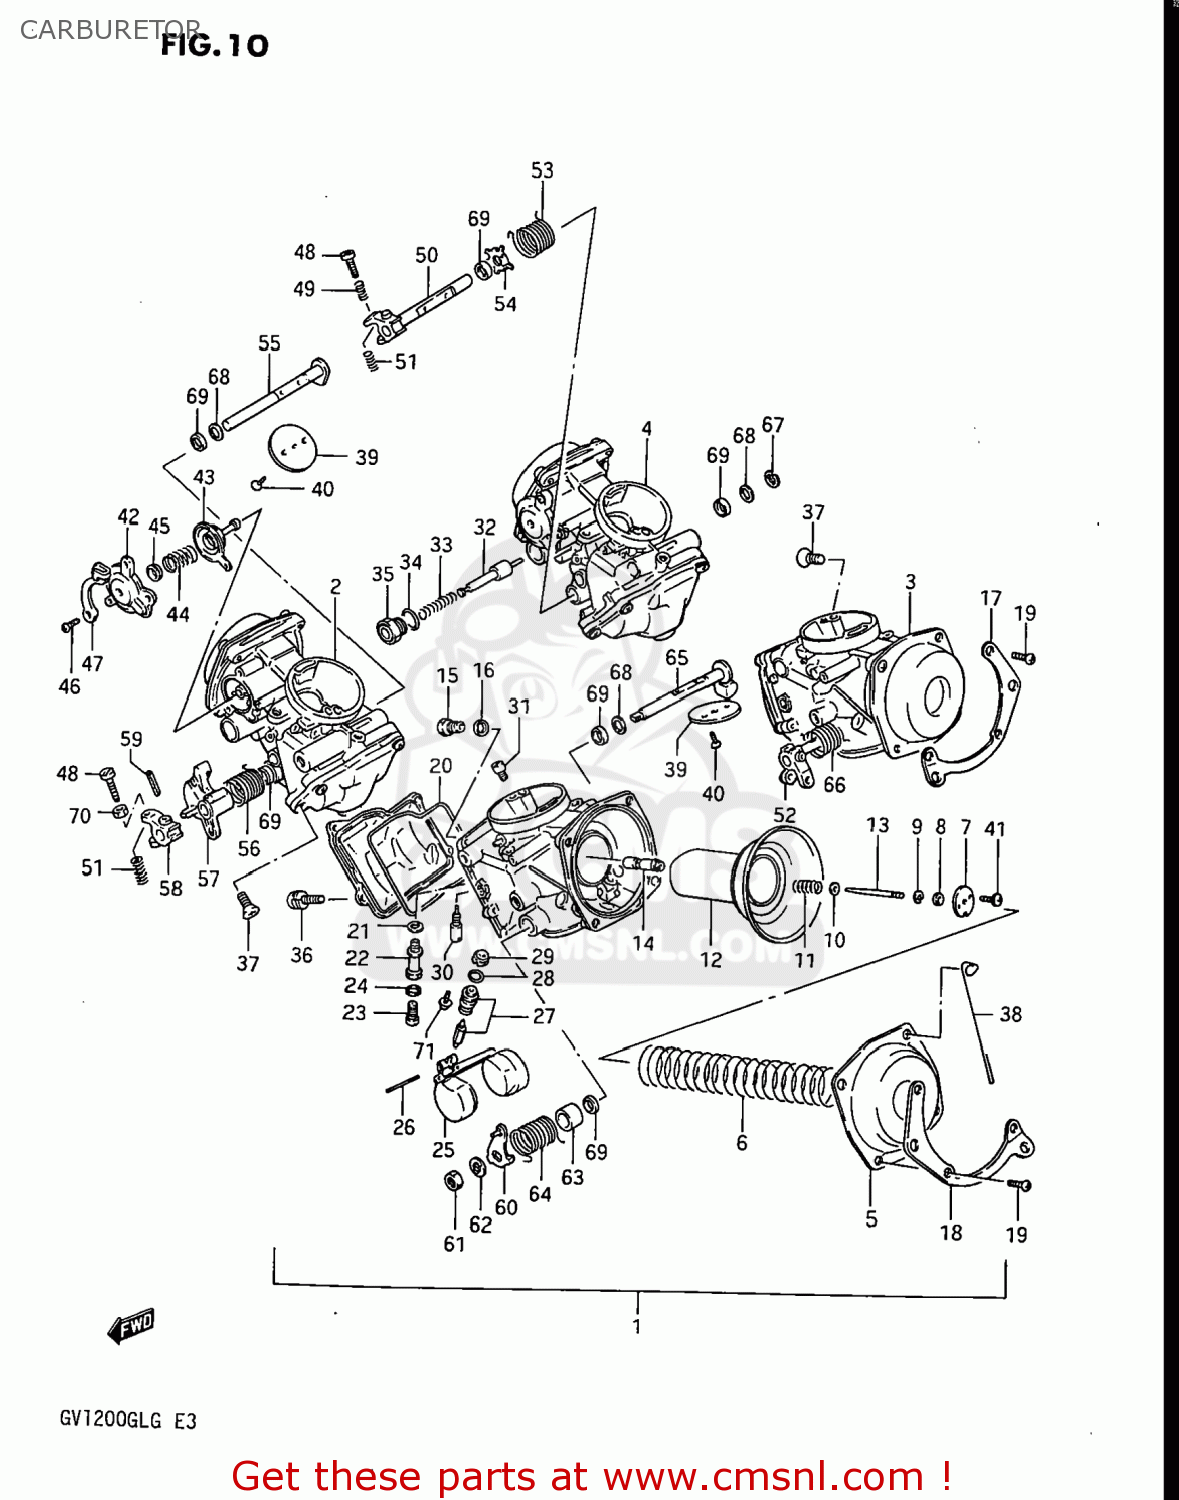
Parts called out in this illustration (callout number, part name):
1	CARBURETOR ASSEMBLY
2	CARBURETOR ASSEMBLY
3	CARBURETOR ASSEMBLY
4	CARBURETOR ASSEMBLY
5	COVER
6	SPRING,DIAPHRAGM
7	PLATE
8	RING
9	CLIP,NEEDLE
10	WASHER
11	SPRING
12	DIAPHRAGM,CARBURETOR
13	NEEDLE JET
14	JET,NEEDLE
15	SCREW
16	WASHER,NEEDLE NOZZLE
17	BRACKET
18	BRACKET
19	SCREW 5X10
20	GASKET,FLOAT CHAMBER
21	GASKET (NAS)
22	HOLDER,MAIN JET
23	JET,MAIN 107,5
24	WASHER
25	FLOAT
26	PIN,FLOAT
27	VALVE ASSEMBLY,NEEDLE
28	O-RING,NEEDLE VALVE
29	FILTER
30	JET,PILOT
31	JET,ENRICH
32	PLUNGER
33	SPRING,STARTER PLUNGER
34	O RING
35	HOLDER,GUIDE
36	SCREW
37	SCREW
38	CLIP
39	VALVE,THROTTLE
40	SCREW
41	SCREW
42	COVER
43	DIAPHRAGM ASSY
44	SPRING
45	PLATE
46	SCREW
47	BRACKET
48	SCREW
49	SPRING
50	SHAFT,THROTTLE
51	SPRING,THROTTLE SCREW
52	SHAFT,THROTTLE
53	SPRING,THROTTLE VALVE
54	PLATE
55	SHAFT,THROTTLE
56	SPRING,THROTTLE VALVE
57	LEVER,THROTTLE
58	LEVER,THROTTLE
59	PIN,THROTTLE SHAFT
60	LEVER,THROTTLE
61	NUT 8MM
62	WASHER
63	RING
64	SPRING,THROTTLE VALVE
65	SHAFT,THROTTLE
66	SPRING,THROTTLE VALVE
67	E RING
68	GASKET,THROTTLE SHAFT (NAS)
69	SEAL,THROTTLE SHAFT
70	NUT
71	SCREW
